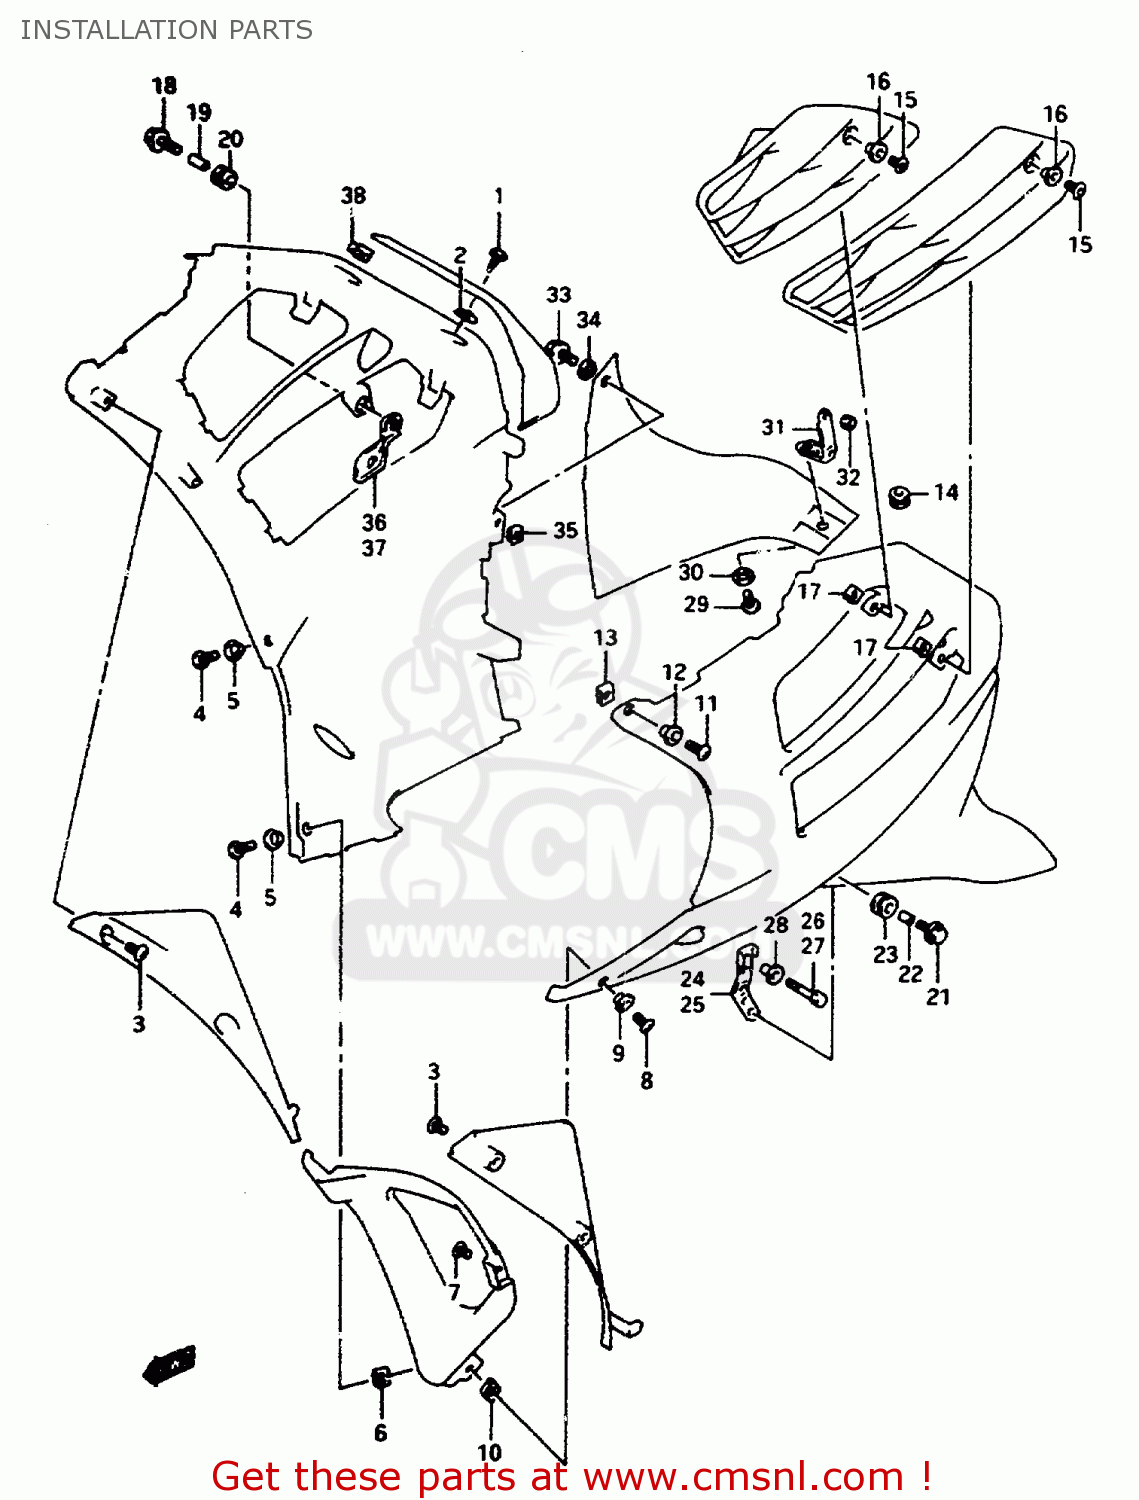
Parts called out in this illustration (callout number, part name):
1	SCREW
2	NUT
3	SCREW 5X10
4	SCREW
5	WASHER(5.2X14X1.5)
6	NUT,HEADLAMP HOUSING,UPPER
7	SCREW 5X10
8	SCREW
9	WASHER(5.2X14X1.5)
10	NUT,HEADLAMP HOUSING,UPPER
11	SCREW
12	WASHER(5.2X14X1.5)
13	NUT,HEADLAMP HOUSING,UPPER
14	CUSHION
15	SCREW
16	WASHER(5.2X14X1.5)
17	NUT,HEADLAMP HOUSING,UPPER
18	BOLT
19	SPACER(6.5X9X10)
20	CUSHION
21	BOLT
22	SPACER(6.5X9X10)
23	CUSHION
24	BRACKET,UNDER COWLING LWR,R
25	BRACKET,UNDER COWLING LWR,L
26	BOLT
27	BOLT
28	SPACER(6.1X10X16)
29	SCREW 5X12
30	WASHER(5.2X14X1.5)
31	BRACKET,RR UNDER COWLING FTG
32	NUT
33	SCREW
34	WASHER(5.2X14X1.5)
35	NUT,HEADLAMP HOUSING,UPPER
36	BRACKET,UNDER COWLING UPR,R
37	BRACKET,UNDER COWLING UPR,L
38	CUSHION,UNDER PANEL
